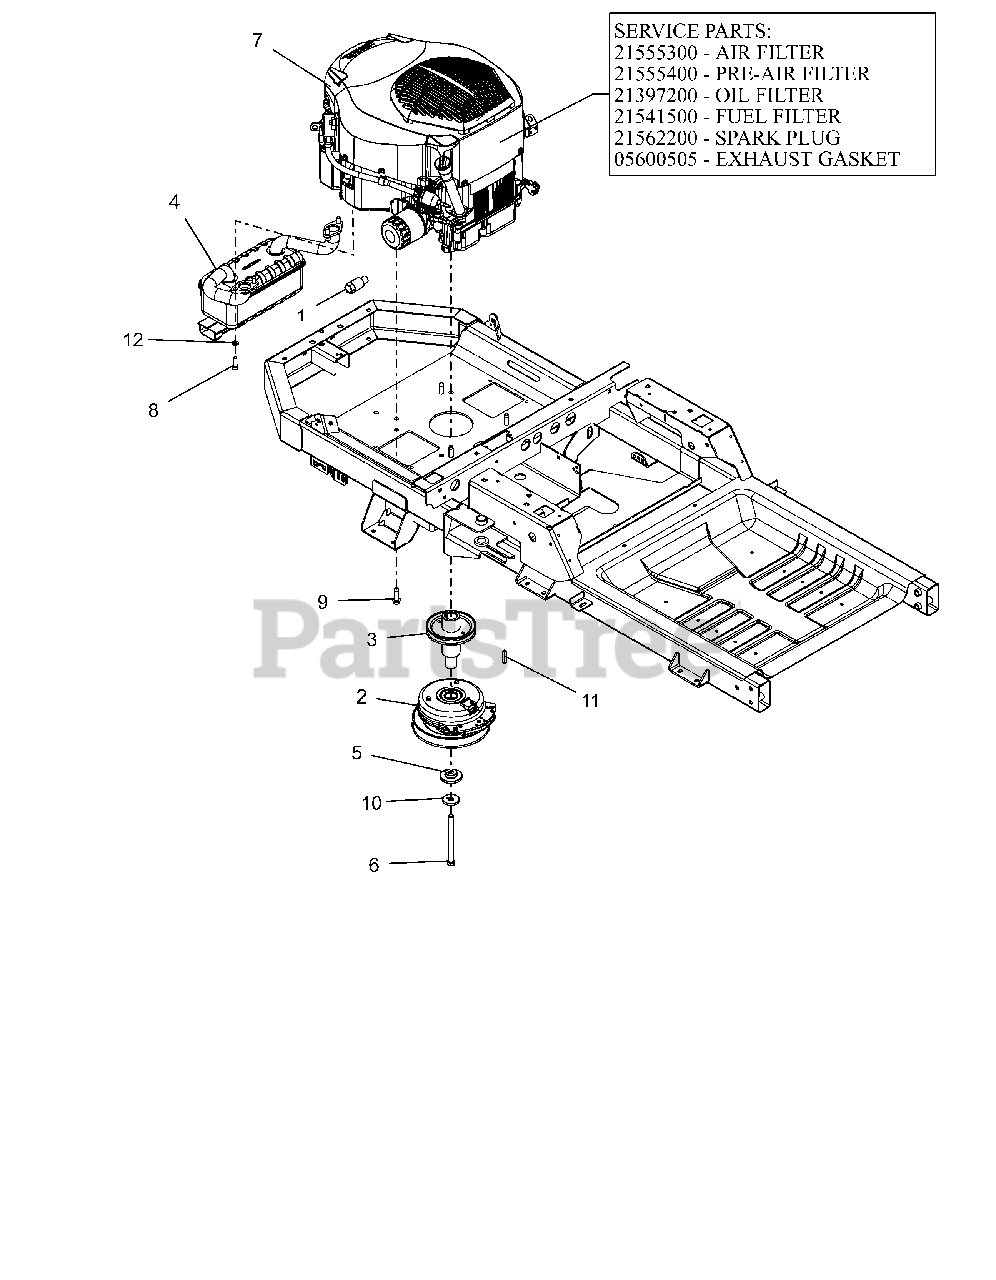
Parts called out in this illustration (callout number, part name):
1	DRAIN, OIL
2	CLUTCH,105FTLB MONOPOLE 6.83"
3	WLDMT, DRIVE SHEAVE (LG XL)CZC
4	MUFFLER, KOHLER
5	BSHG-FLG .469X1.06X.574X2.0
6	BLT-HEX.438-20X5 GR8 YZ NYTORQ
7	ENGINE,KOHLER TWIN 25 PRO W/SC
7	AIR FILTER, KOHLER
7	PRE CLEANER, KOHLER
7	FILTER, OIL - KOH CV20
7	FILTER, FUEL
7	PLUG, SPARK (RFI)
7	GASKET, MUFFLER KOHLER TWIN
8	SCR, SKH .312-18X.875 GR8 ZCC
9	SCR,TAP .375-16X1.25HWH TR ZCC
10	WASHER, 7/16" SPRING DISK
11	KEY-SQ .25 X 1.25 X .25 SAE
12	WSHR,LK-REG .312X.078 ZCC
